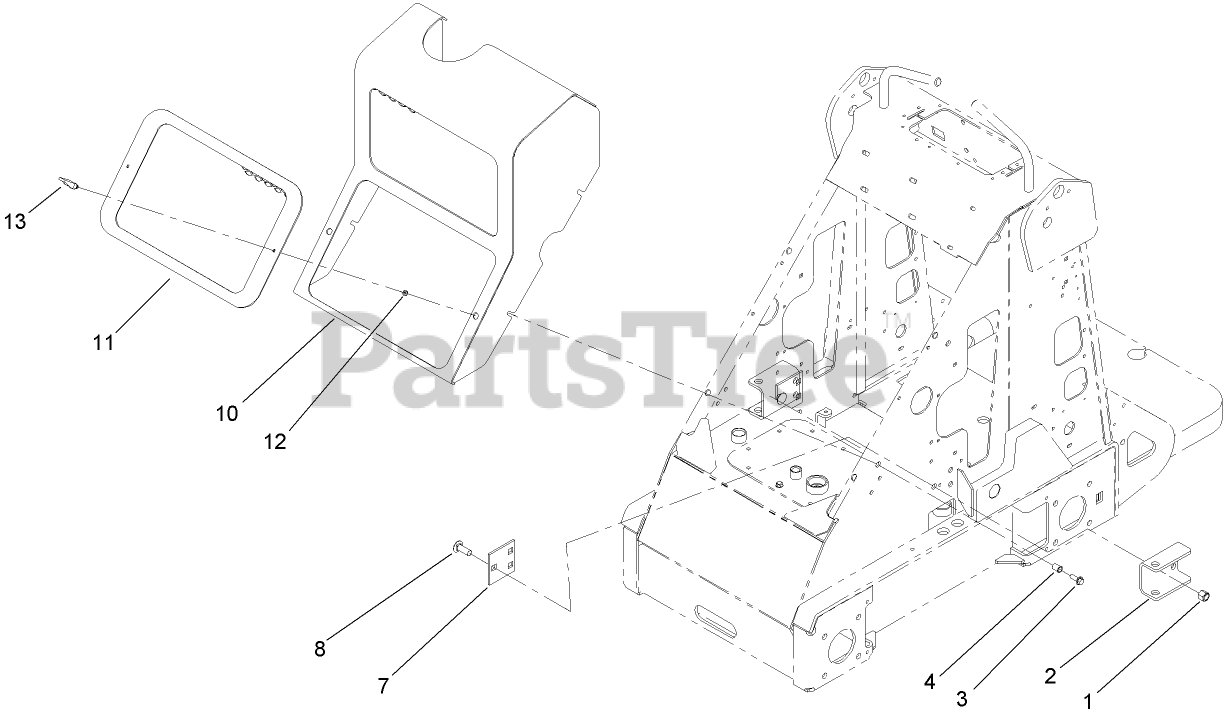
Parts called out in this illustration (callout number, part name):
1	NUT-LOCK, NI
2	BRACKET-ANCHOR
3	SCREW-HHF
4	INSERT-THREADED
7	PLATE-ANCHOR
8	SCREW-CARR, SHORT NECK
12	WASHER
13	LATCH-SWELL
